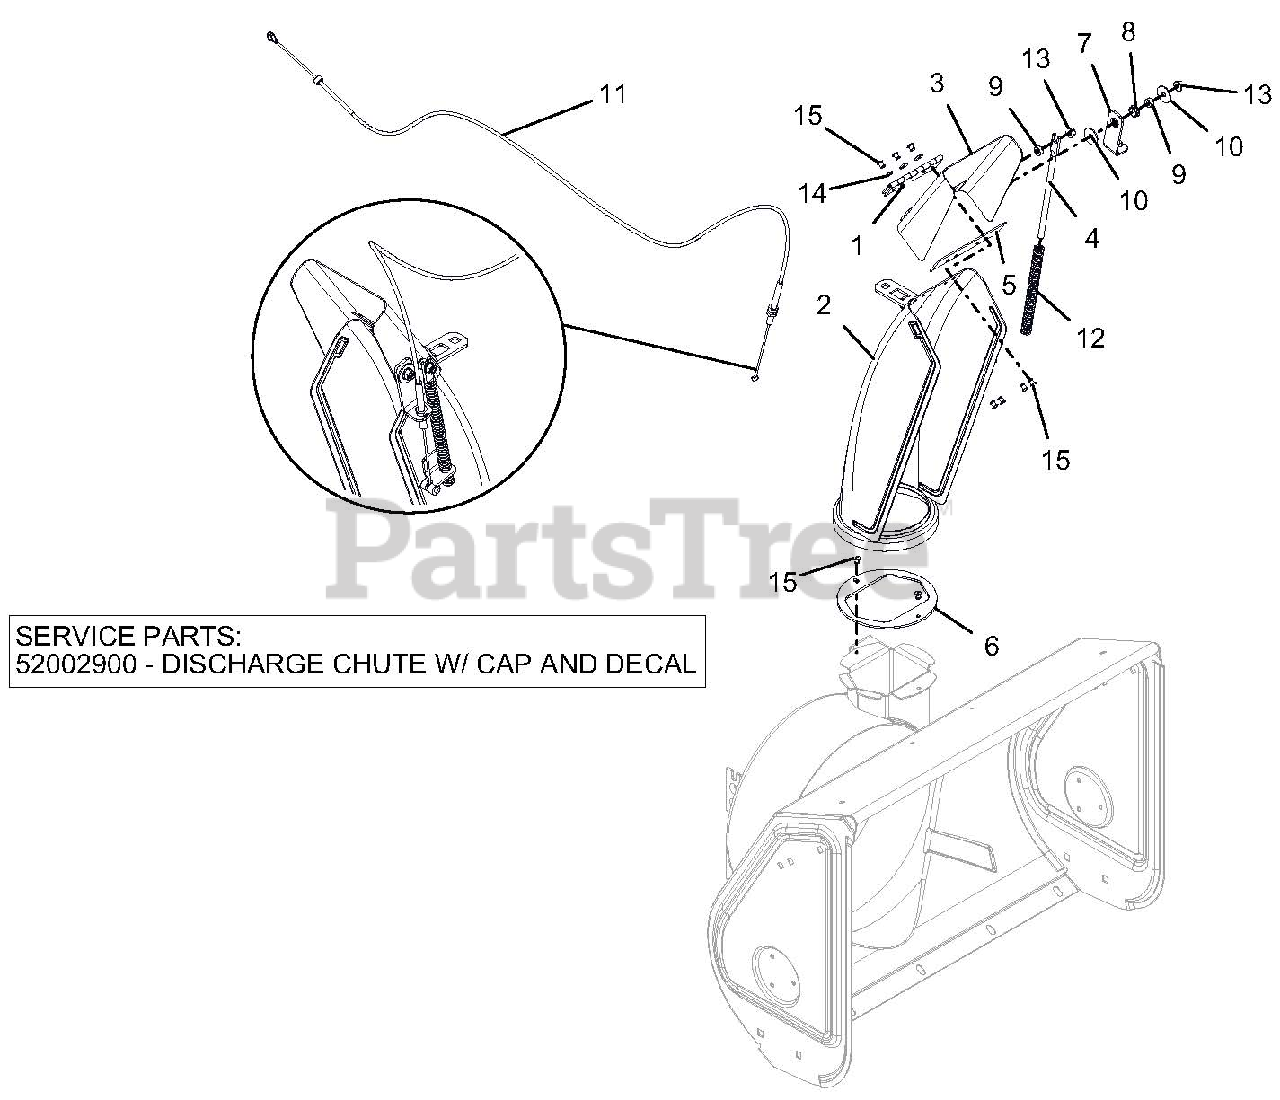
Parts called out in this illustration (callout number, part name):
2	CHUTE, COMPACT-TALL W/REMOTE
3	CAP, COMPACT-W/REMOTE
4	ROD, DEFLECTOR CAP
5	CAP SEAL 5.25
6	BAFFLE, COMPACT DISCHARGE
7	BRACKET, CABLE ANCHOR
8	BUSHING, POLYLINER-.50 SNAPIN
9	BSHG-SLV .265X.500X.219
10	WSHR-FL-STL .281X1.000X.063
11	CABLE, DEFLECTOR - COMPACT
12	SG-COMP .08X.40X6.50 14#/IN
13	@NUT-LK-TOP-FLG .25-20 YWZC
14	WSHR-FL-STL .196X.500X.06 YZ
15	RVT-POP .187 YZ
16	CHUTE, DISCHARGE W/REM.CAP,DEC
